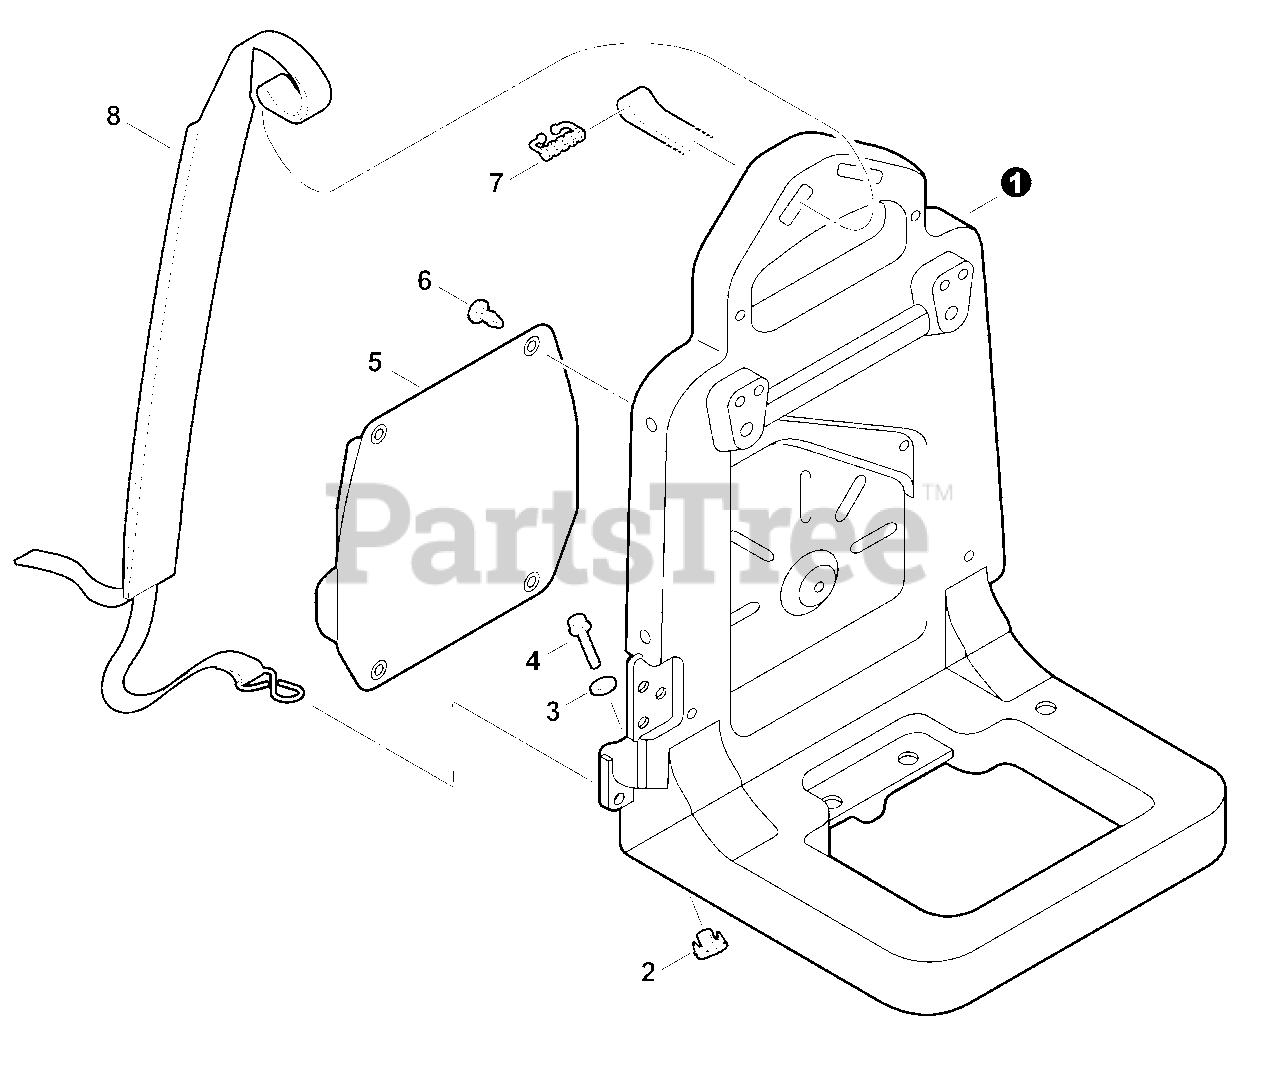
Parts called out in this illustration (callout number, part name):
1	FRAME, BACKPACK
3	WASHER - 6
4	SCREW - 6×25
5	CUSHION, BACKPACK
7	RETAINER, HARNESS
8	BACKPACK STRAP ASSY
